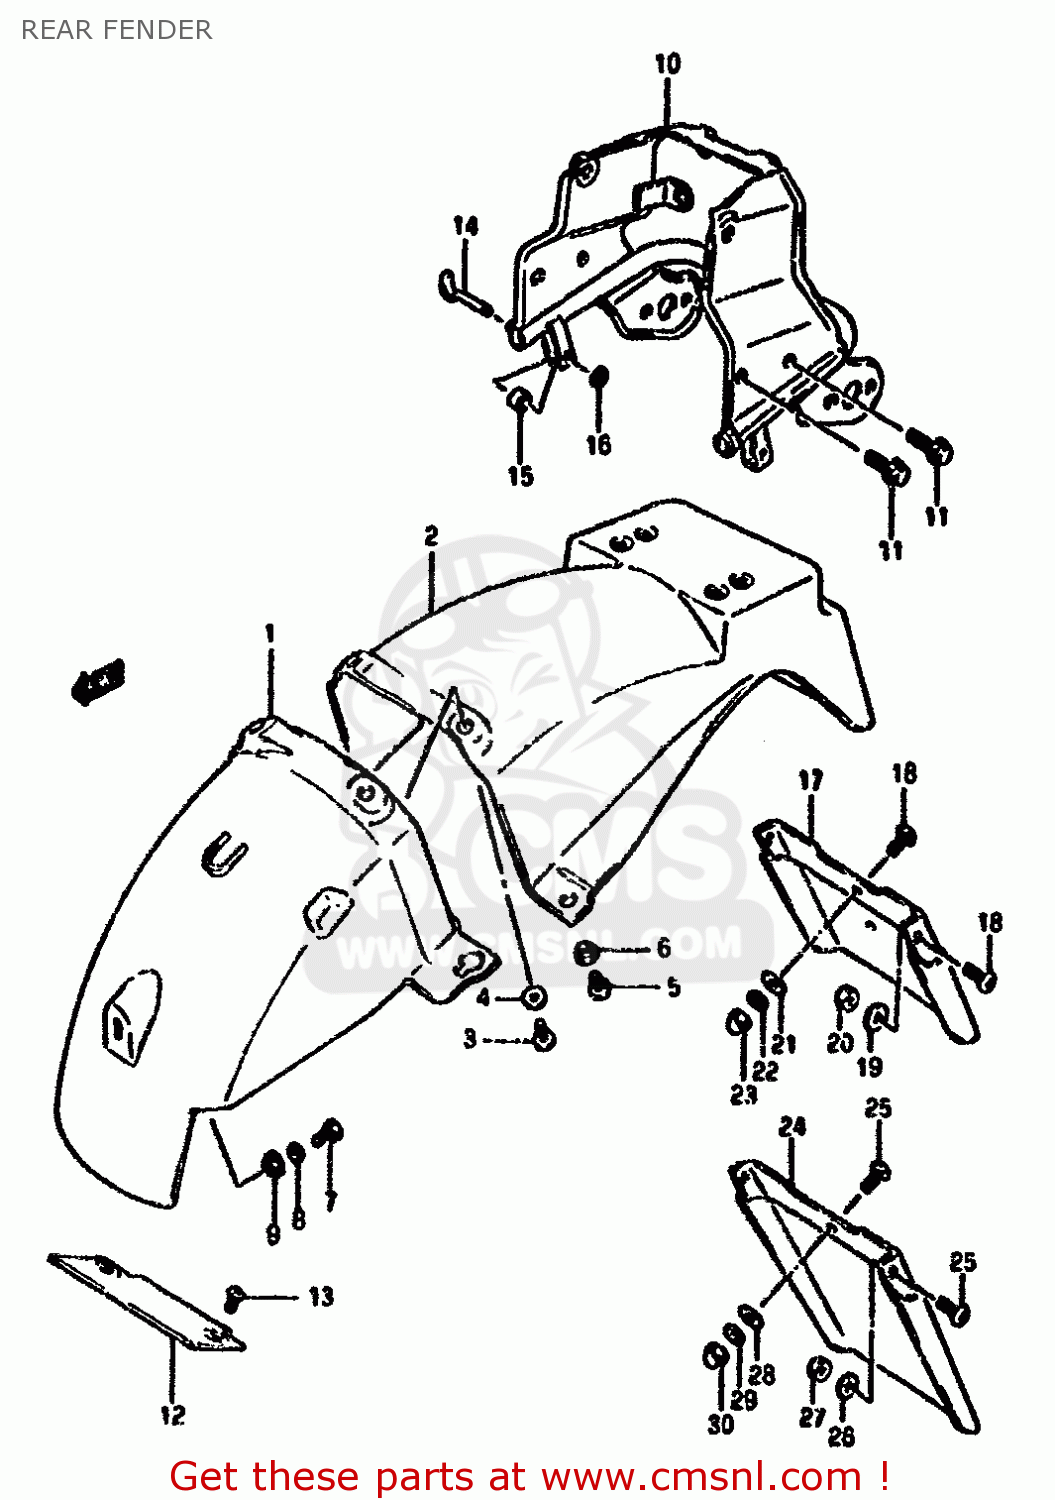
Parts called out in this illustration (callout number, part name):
1	BODY,REAR FENDER,FRONT
2	BODY,REAR FENDER REAR
3	SCREW
4	WASHER
5	SCREW
6	WASHER
7	BOLT
8	WASHER,LOCK
9	WASHER
10	REINF,RR FENDER
11	BOLT
12	GUARD,REAR FENDER,FRONT
13	SCREW
14	ROD,GRIP
15	SPACER,GRIP ROD
16	E RING
17	EXTENSION, REAR FENDER
18	SCREW
19	WASHER
20	NUT
21	WASHER (6.5X18X1.6)
22	WASHER
23	NUT 6MM
24	MUD GUARD
25	SCREW
26	WASHER(6.5X16X1.2)
27	NUT
28	WASHER (6.5X18X1.6)
29	WASHER
30	NUT 6MM
